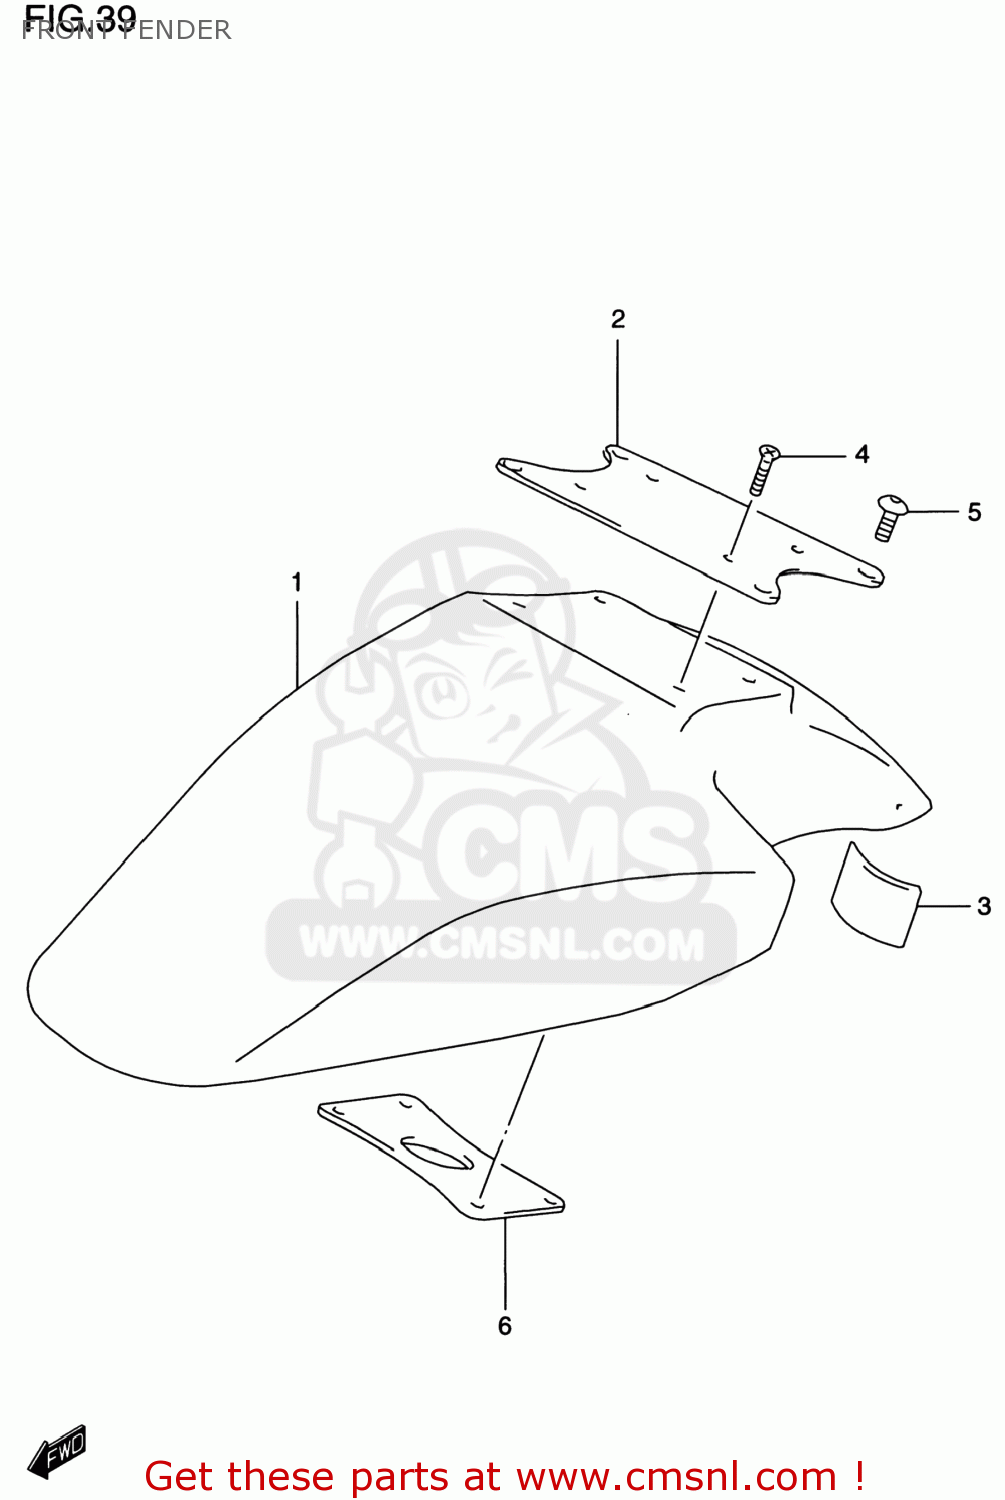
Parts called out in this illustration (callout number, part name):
1	FENDER,FRONT
2	BRACE,FR FENDER
3	CUSHION,FR FENDER
4	SCREW(5X18)
5	SCREW(8X16)
6	BRACE,FR FENDER INNER
